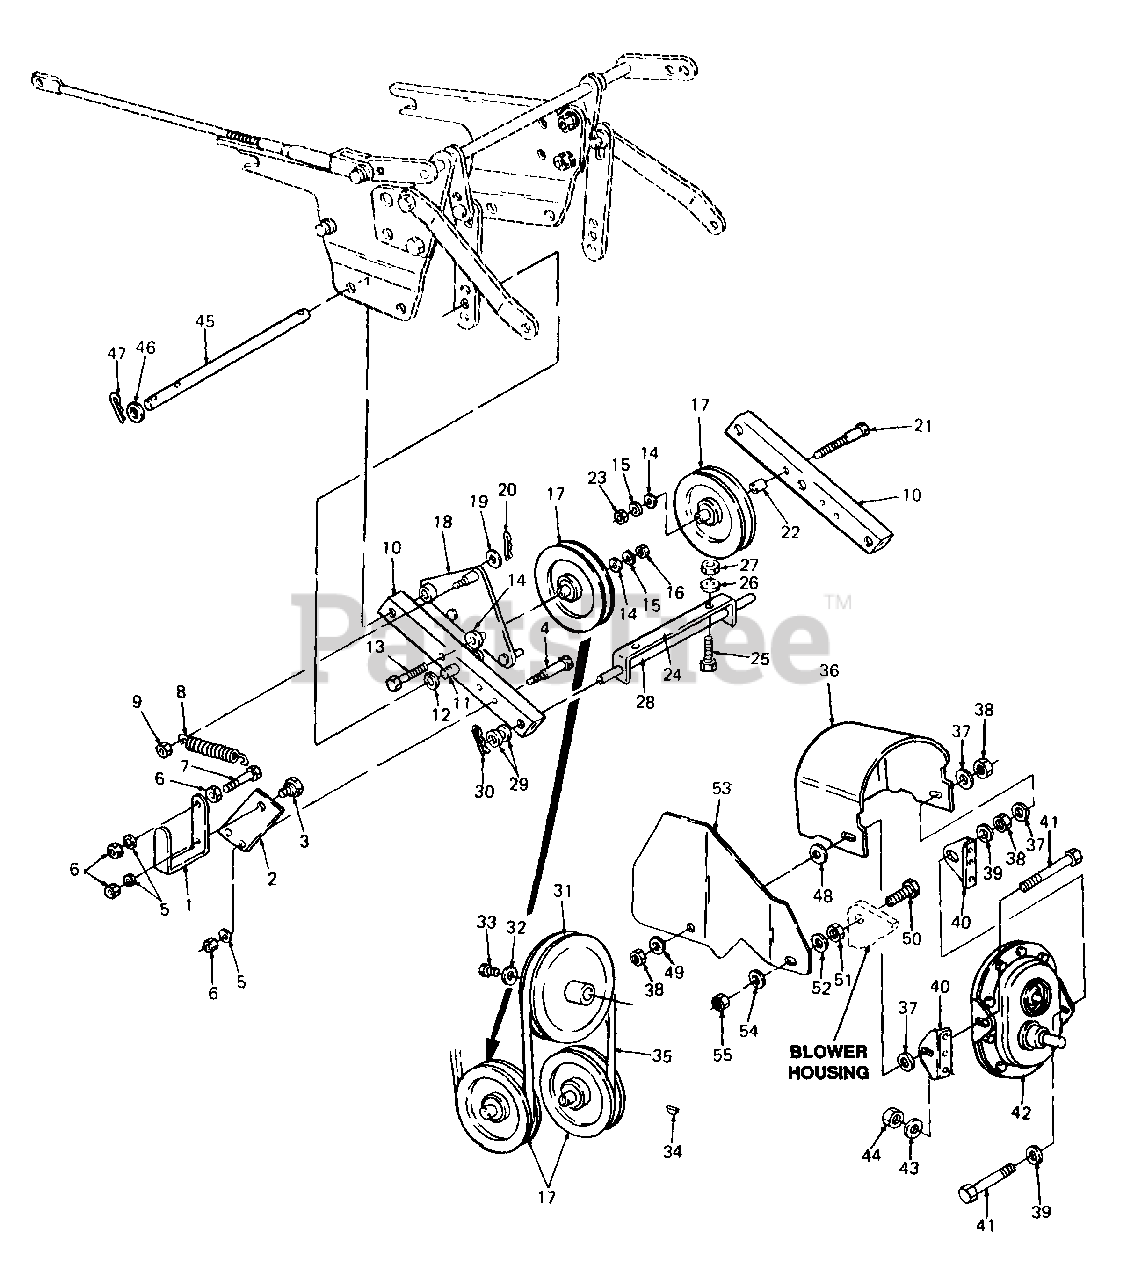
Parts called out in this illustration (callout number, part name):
3	Bolt, Shoulder, .625 Dia X .217 Lg
4	Screw, Hex Cap, 3/8-16 X 3.0 Lg
5	Washer, Lock, 3/8
6	Nut, Hex, 3/8-16
7	Screw, Hex Cap, 3/8-16 X 2.25 Lg
8	Spring, Extension
9	Nut, Hex Insert Lock, 3/8-24
10	Tubing, Square
11	Pin, Clevis
12	Washer, Flat, .625 X 1.0 X .067 Thk
13	Screw, Hex Cap, 1/2-13 X 2.0 Lg
14	Washer, Flat, .510 X 1.0 X .12 Thk
15	Washer, Lock, 1/2
16	Nut, Hex, 1/2-13
17	Pulley, Idler, .50 ID X 6.0 OD
20	Pin, Hitch Clip
21	Screw, Hex Cap, 1/2-20 X 4.5 Lg GR5
22	Spacer, .50 X .75 X .780 Lg
23	Nut, Hex,1/2-20
24	Pivot Brkt, Blower Hsg
25	Screw, Hex Cap, 1/2-20 X 1.25 Lg
26	Washer, Lock, 1/2
27	Nut, Hex Jam, 1/2-20
28	Rod, 12.5 Lg
29	Washer, Flat, .625 X 1.0 X .067 Thk
30	Pin, Hitch Clip
33	Screw, Hex Patch, 3/8-24 X 1.0 Lg GR5
34	Key, Hi-Pro, 1/4 X 3/4
35	Belt, 5/8 X IC 84.0 Lg
36	Cover, Belt
37	Washer, Flat, .344 X .88 X .063 Thk
38	Nut, Hex, 5/16-18
39	Washer, Belleville, .345 X .88 X .060 Thk
40	Bracket, Gear Box Support
41	Screw, Hex Cap, 5/16-18 X 1.25 Lg GR5
42	Gear Box Assy
43	Washer, Lock, 1/4
44	Nut, Hex, 1/4-28
45	Rod, 12.5 Lg
46	Washer, Flat, .625 X 1.0 X .067 Thk
47	Pin, Hitch Clip
48	Washer, Flat, .330 X 1.25 X .120 Thk
49	Washer, Belleville, .325 X .930
50	Screw, Hex Cap, 3/8-16 X 1.25 Lg
51	Nut, Hex Jam, 3/8-16
52	Washer, Flat, .385 X .87 X .06 Thk
53	Deflector, Exhaust
54	Washer,Belleville, .38O X .88 X .062 Thk
55	Nut, Hex, 3/8-16 GR5
